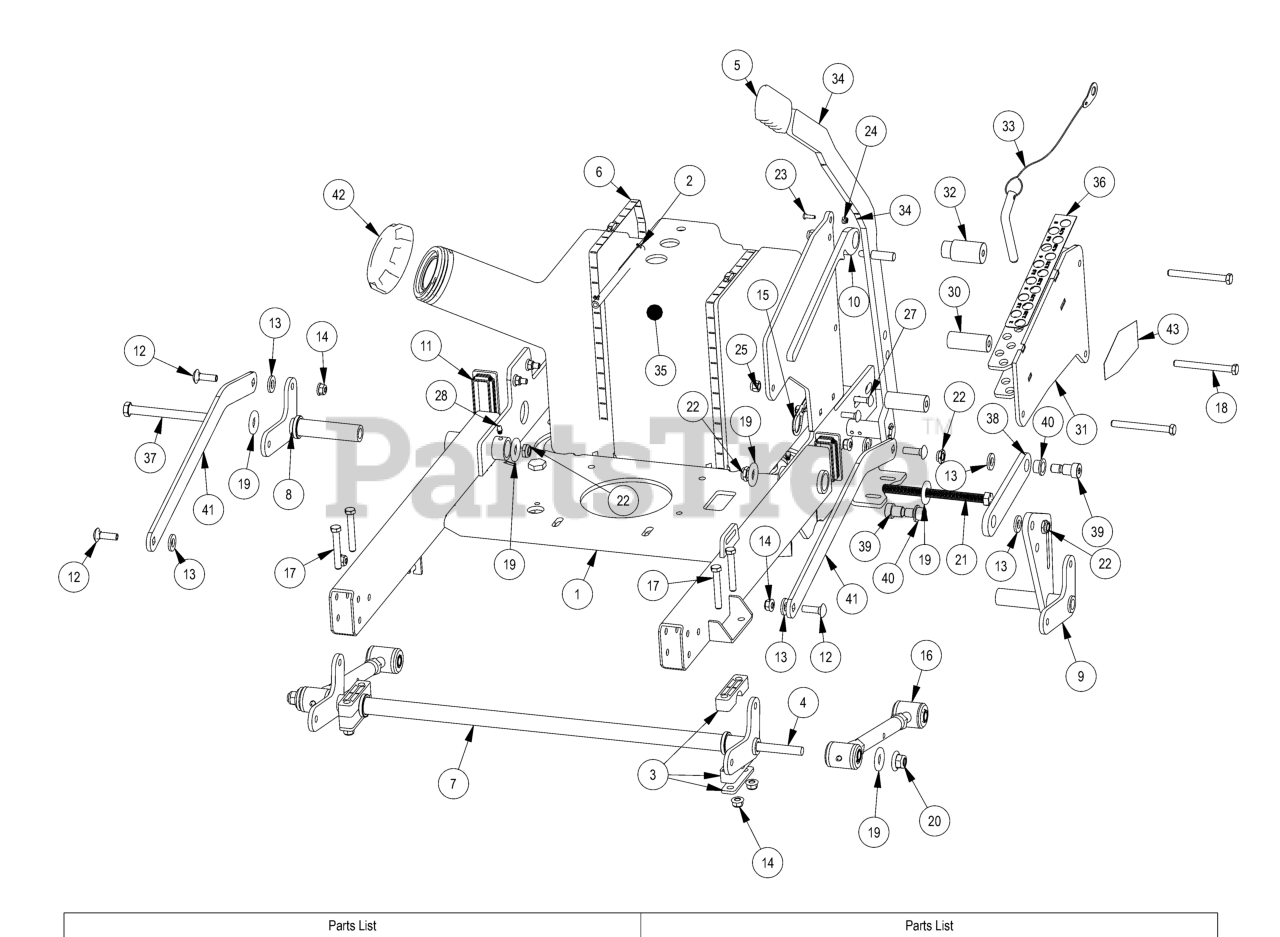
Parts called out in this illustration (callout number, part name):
1	2020 36" Stand On Frame
2	Revolt Fuel Line Assembly
3	Pillow Block Kit
4	2020 36 Stand On Turnbuckle Rod
5	2019 Stand On Lift Grip
6	2019 Stand On Gas Tank Strap
7	Revolt Front Actuator Bar Weldment 2020 36" Black
8	Revolt Rear Actuator Bar Weldment RH 2020 36" Black
9	Revolt Rear Actuator Bar Weldment LH 2020 36" Black
10	2019 Stand On Deck Lever Lock
11	1 1/2 x 3 Frame Plug
12	3/8-16 X 1-1/4 CARRIAGE BOLT ZINC
13	.505 ID X 1.000 OD X .125 THICK FLAT WASHER NYLON
14	3/8" Nylock Flange Nut
15	Revolt Cotter Pin for 7/8" to 1" shank
16	2018 Maverick Turnbuckle (Top Link)
17	3/8-16 X 2-1/2 HEX CAP SCREW (GR.5) ZINC
18	3/8-16 X 3-3/4 HEX CAP SCREW (GR.5) ZINC
19	1/2" Flat Washer
20	1/2-13 NYLON INSERT FLANGE LOCKNUT ZINC
21	1/2-13 x 6 1/2 Hex Bolt
22	1/2''-13 Jam Nut
23	10-24 X 5/8 BUTTON SOCKET CAP SCREW 18-8 STAINLESS STEEL
24	10-24 NYLON INSERT LOCKNUT ZINC
25	3/8 Nylock Nut
26	5/16" Nylock Flange Nut Zinc
27	5/16-18 X 1 CARRIAGE BOLT (GR.8) ZINC
28	1/4" Press in Grease Fitting
29	2023 Stand On Inner Adjustment Plate
30	Stand On Spacer 2.5''
31	2023 Stand On Outer Adjustment Plate weldment
32	Stand On Spacer 2.5'' With shoulder
33	2023 stand on Height Adj Pin
34	2023 Stand On SD Lift Lever Weldment
36	2023 Revolt Deck Hight decal
37	1/2-13 X 5 1/2 HEX CAP SCREW (GR.5) ZINC
38	2023 lever secondary linkage
39	5/8'' x 5/8'' Shoulder Bolt
40	.627 ID X .753 OD X .500 LGTH X 1.000 FLG OD X .094 FLG THICK
41	2023 SD-36 Stand-on Actuator Linkage
43	Revolt Deck Height Decal
